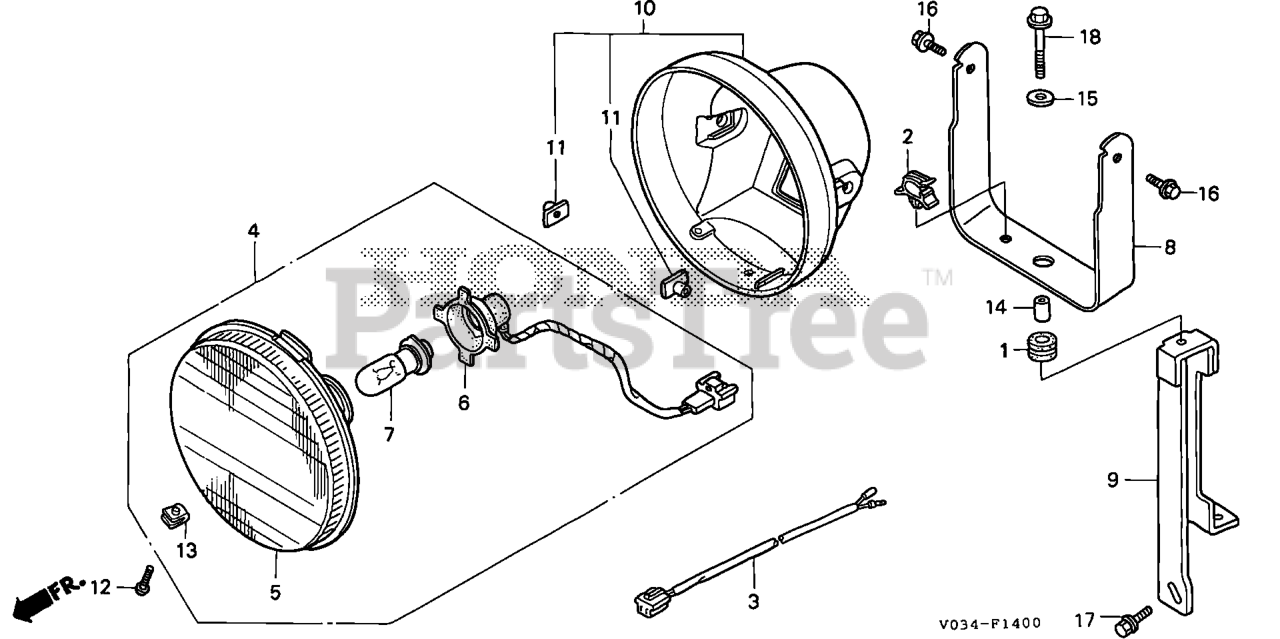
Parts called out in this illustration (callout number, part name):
1	GROMMET, OIL COOLER
2	CLIP, WIRE HARNESS
3	WIRE ASSY., WORK LIGHT
4	HEADLIGHT ASSY.
5	HEADLIGHT UNIT
6	SOCKET ASSY., HEADLIGHT
7	BULB, HEADLIGHT (12V 15/15W)
8	BRACKET, HEADLIGHT
9	STAY, HEADLIGHT
10	CASE ASSY., HEADLIGHT
11	NUT, SPECIAL (6X7)
12	SCREW, PAN (5X16)
13	NUT, SPRING (5MM)
14	COLLAR, RR. TURN SIGNAL MOUNTING
15	WASHER, PLAIN (8MM)
16	BOLT, FLANGE (6X12)
17	BOLT, FLANGE (6X16) Use from Engine SN 2056820.
18	BOLT, FLANGE (8X30)
